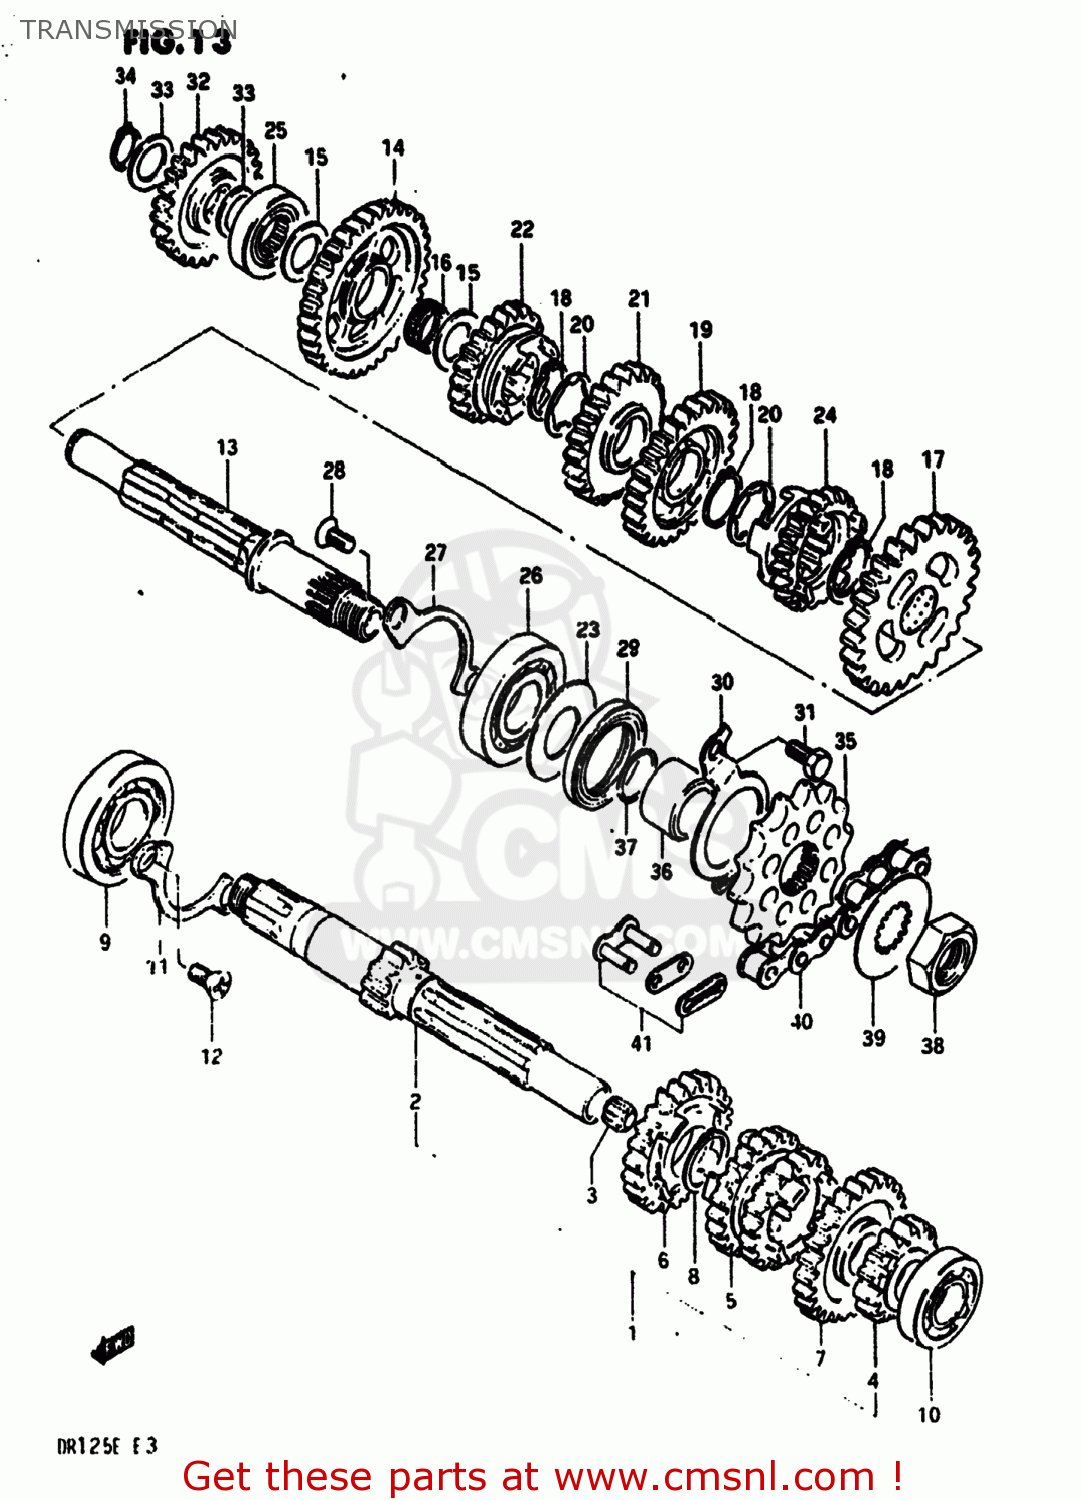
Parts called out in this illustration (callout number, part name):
1	SHAFT,COUNTER
2	SHAFT,COUNTER
3	BUSHING
4	GEAR,SECOND DRIVE
5	GEAR,THIRD & FOURTH DRIVE,N
6	GEAR,FIFTH DRIVE
7	GEAR,SIXTH DRIVE
8	CIRCLIP
9	BEARING
10	BEARING, LH
11	RETAINER,DRIVE SHAFT BEARING
12	SCREW
13	SHAFT,DRIVE
14	GEAR,FIRST DRIVEN
15	WASHER
16	BEARING(15X19X7.8)
17	GEAR,SECOND DRIVEN
18	CIRCLIP
19	GEAR,THIRD DRIVEN
20	WASHER,LOCK
21	GEAR,FOURTH DRIVEN
22	GEAR,FIFTH DRIVEN
23	WASHER,OIL SEALING
24	GEAR,SIXTH DRIVEN
25	BEARING(15X33X12)
26	BEARING
27	RETAINER,DRIVE SHAFT BEARING
28	SCREW
29	SEAL,OIL(27X40X6)
30	PLATE,DRIVESHAFT OIL
31	BOLT
32	GEAR,KICK STARTER IDLE(NT:26)
33	WASHER
34	CIRCLIP,15MM
35	SPROCKET,ENGINE
36	SPACER
37	O RING(D:2.4,ID:19)
38	NUT
39	WASHER,LOCK
40	CHAIN ASSEMBLY,DRIVE
41	JOINT SET,CHAIN
